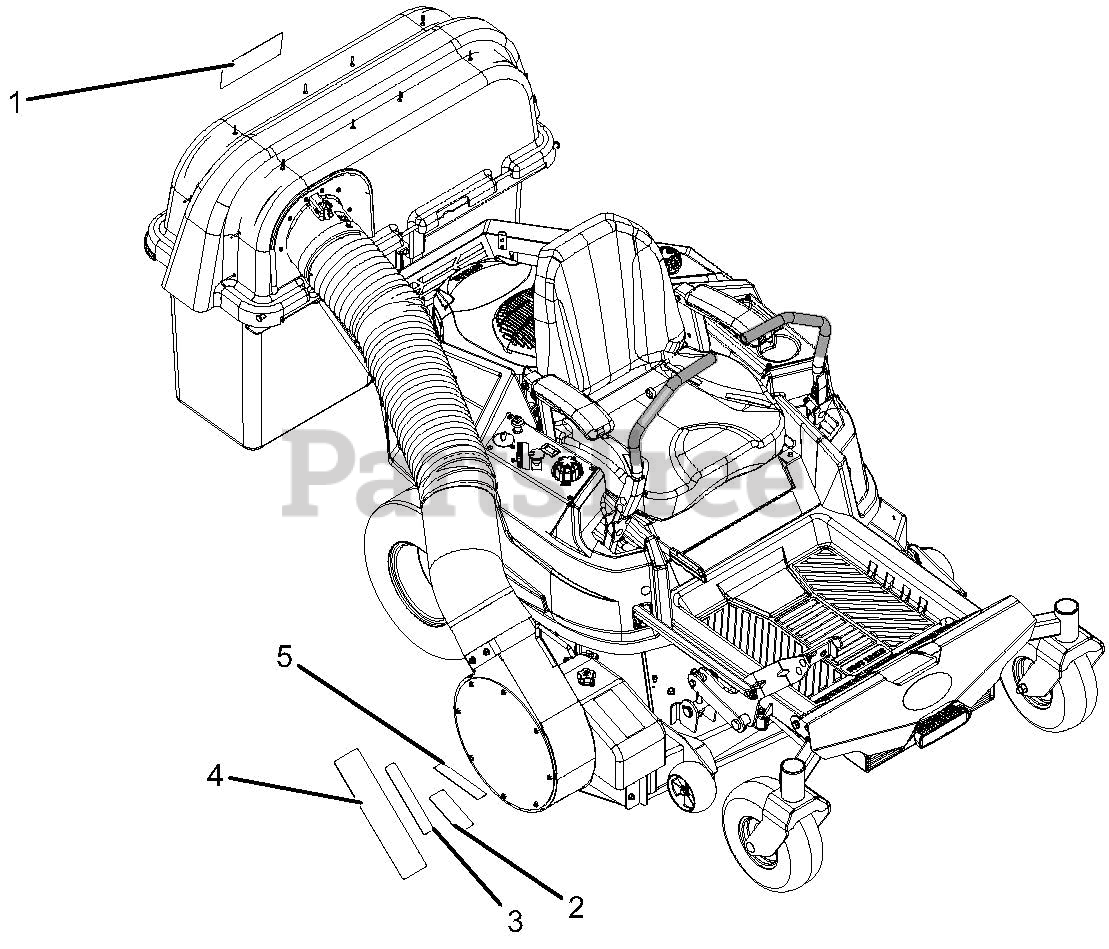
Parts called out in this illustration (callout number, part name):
1	DECAL, BAGGER COVER
2	DECAL, MOWER PAN DANGER
3	DECAL, DANGER
4	DECAL, CAUTION GRASS PUMP
5	DECAL, WARNING
